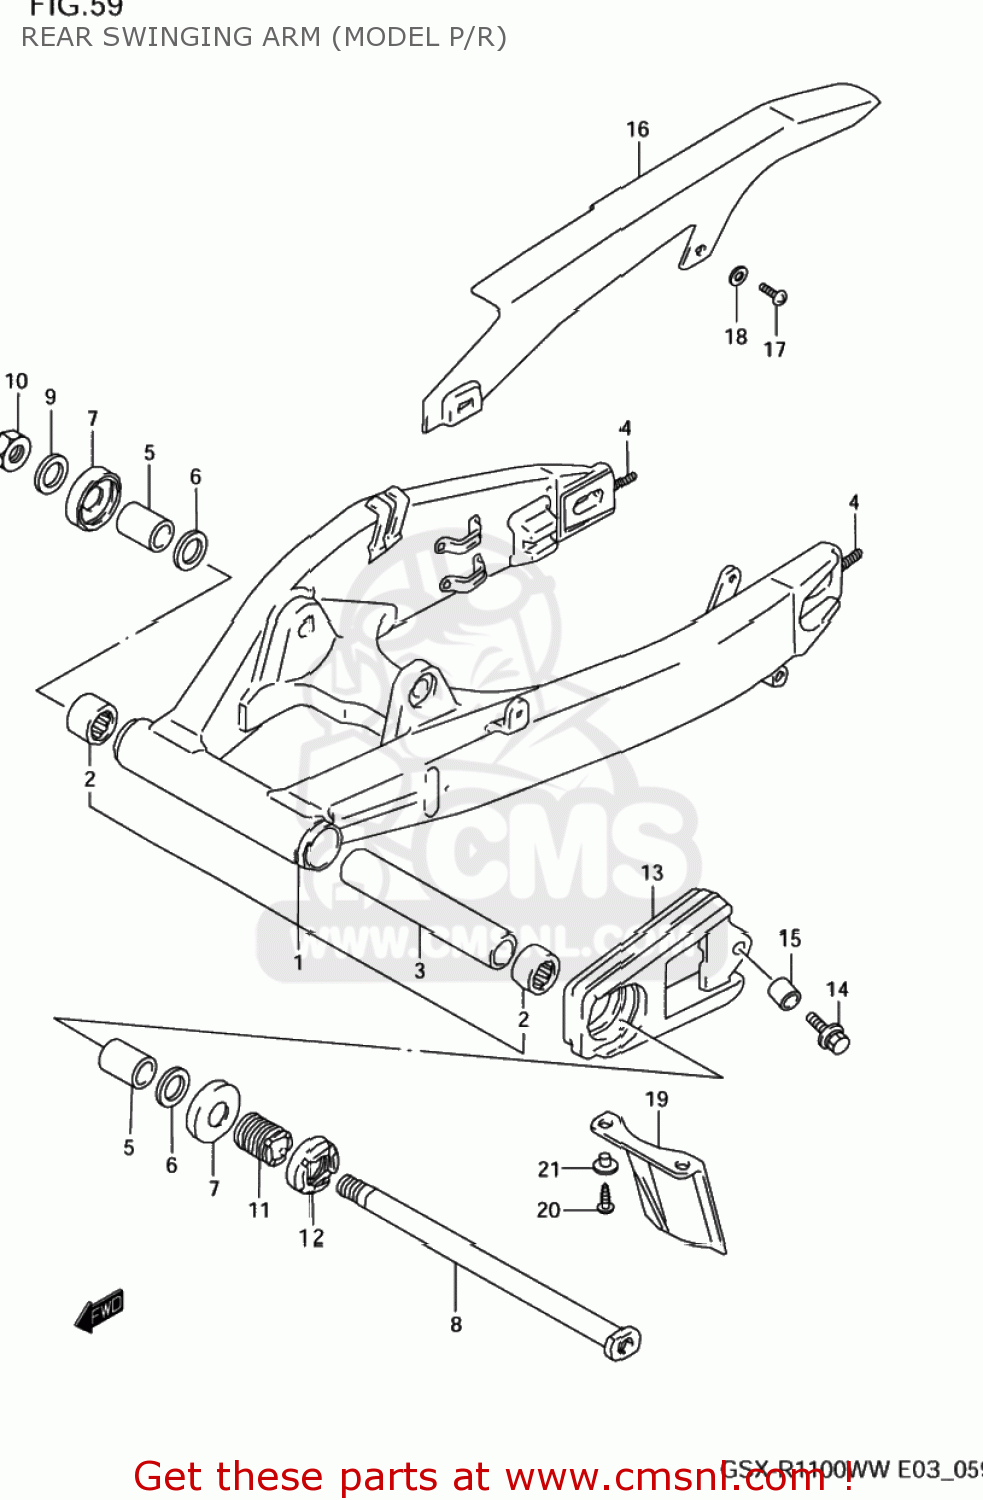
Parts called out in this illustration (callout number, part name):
1	SWINGINGARM ASSY,RR
2	BEARING(25X33X30)
3	SPACER,RR SWGARM PIVOT CTR
4	STUD,CHAIN ADJUSTER BOLT
5	SPACER,RR SWGARM PIVOT BERRING
6	WASHER
7	DUST SEAL,RR SWGARM PIVOT
8	SHAFT,REAR SWING ARM
9	WASHER
10	NUT
11	BOLT,RR SWGARM PIVOT
12	NUT,REAR SWING ARM PIVOT
13	BUFFER,CHAIN TOUCH DEFENSE
14	BOLT 6X20,WITH PLAIN WASHER
15	SPACER
16	CASE,CHAIN
17	SCREW
18	WASHER
19	GUARD,RR UNIT MUD
20	SCREW
21	WASHER
